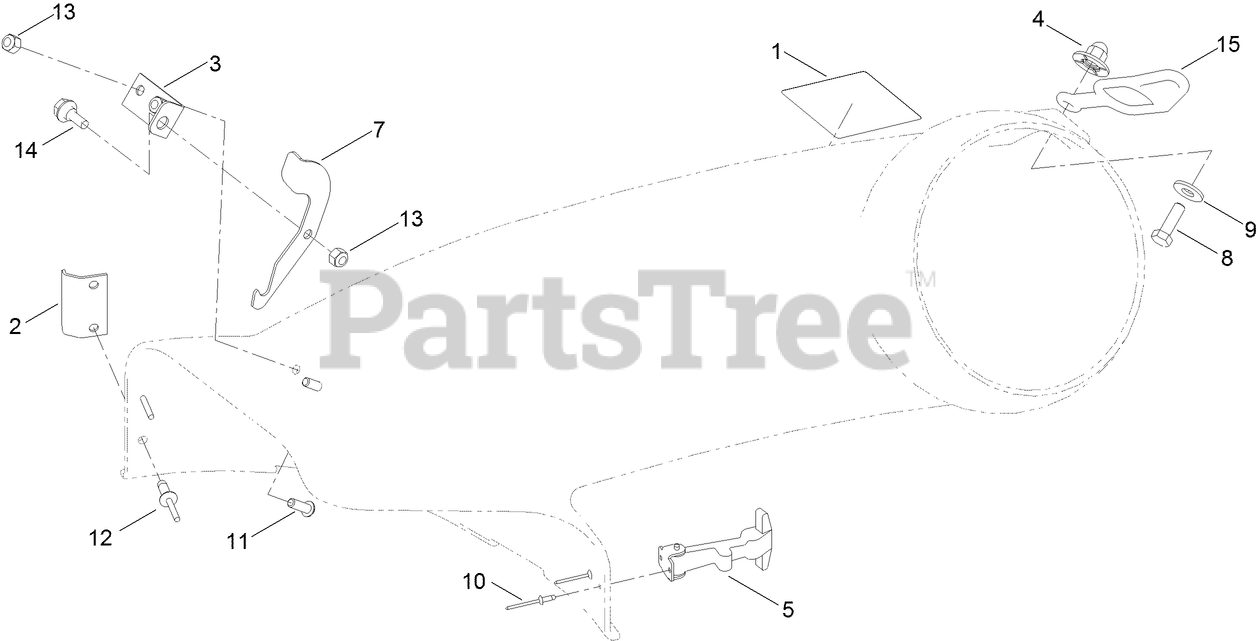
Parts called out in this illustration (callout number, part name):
1	DECAL-DANGER
2	BRACKET-ELBOW
3	PLATE-PIVOT, CZ
4	NUT-IMPELLER
5	HANDLE ASM
8	SCREW-HH
9	WASHER-FLAT
10	RIVET-POP
11	SCREW-HSBH
12	RIVET-BLIND
13	NUT-HEX
15	RETAINER-DUCT
